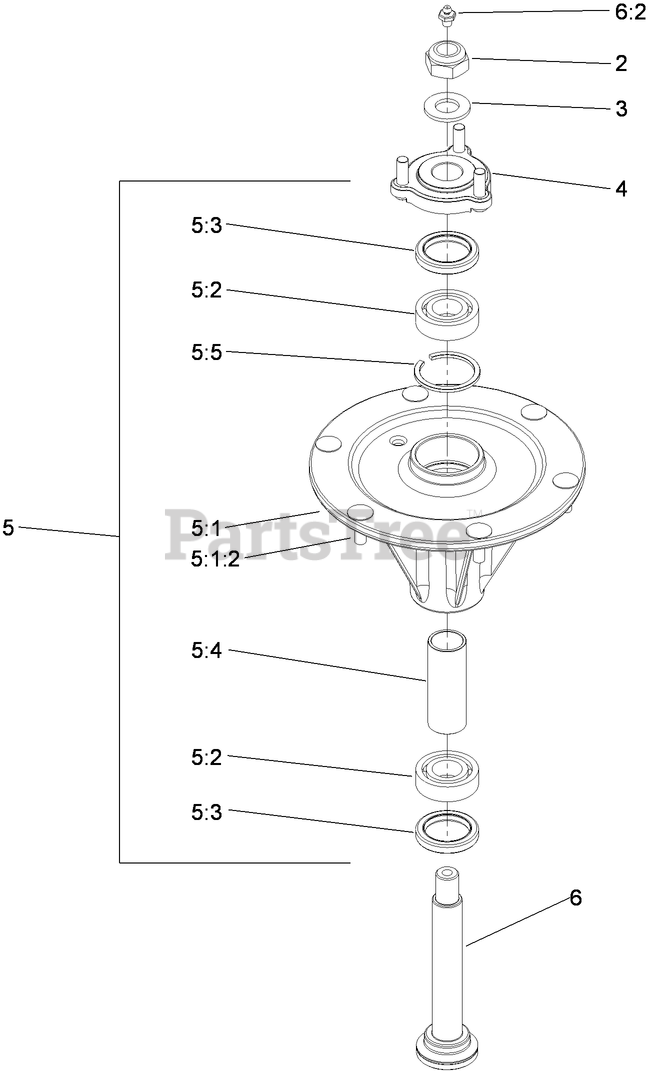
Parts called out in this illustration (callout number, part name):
2	NUT-LOCK, NI
3	WASHER
4	SPINDLE HUB ASM
5	SPINDLE HOUSING AND BALL BEARING ASM
5:1	SPINDLE HOUSING AND STUDS ASM
5:1:2	BOLT-RIBBED NECK
5:2	BEARING-BALL
5:3	SEAL-OIL
5:4	SPACER
5:5	RING-SNAP
6	SPINDLE SHAFT AND ZERK ASM
6:2	FITTING-GREASE
